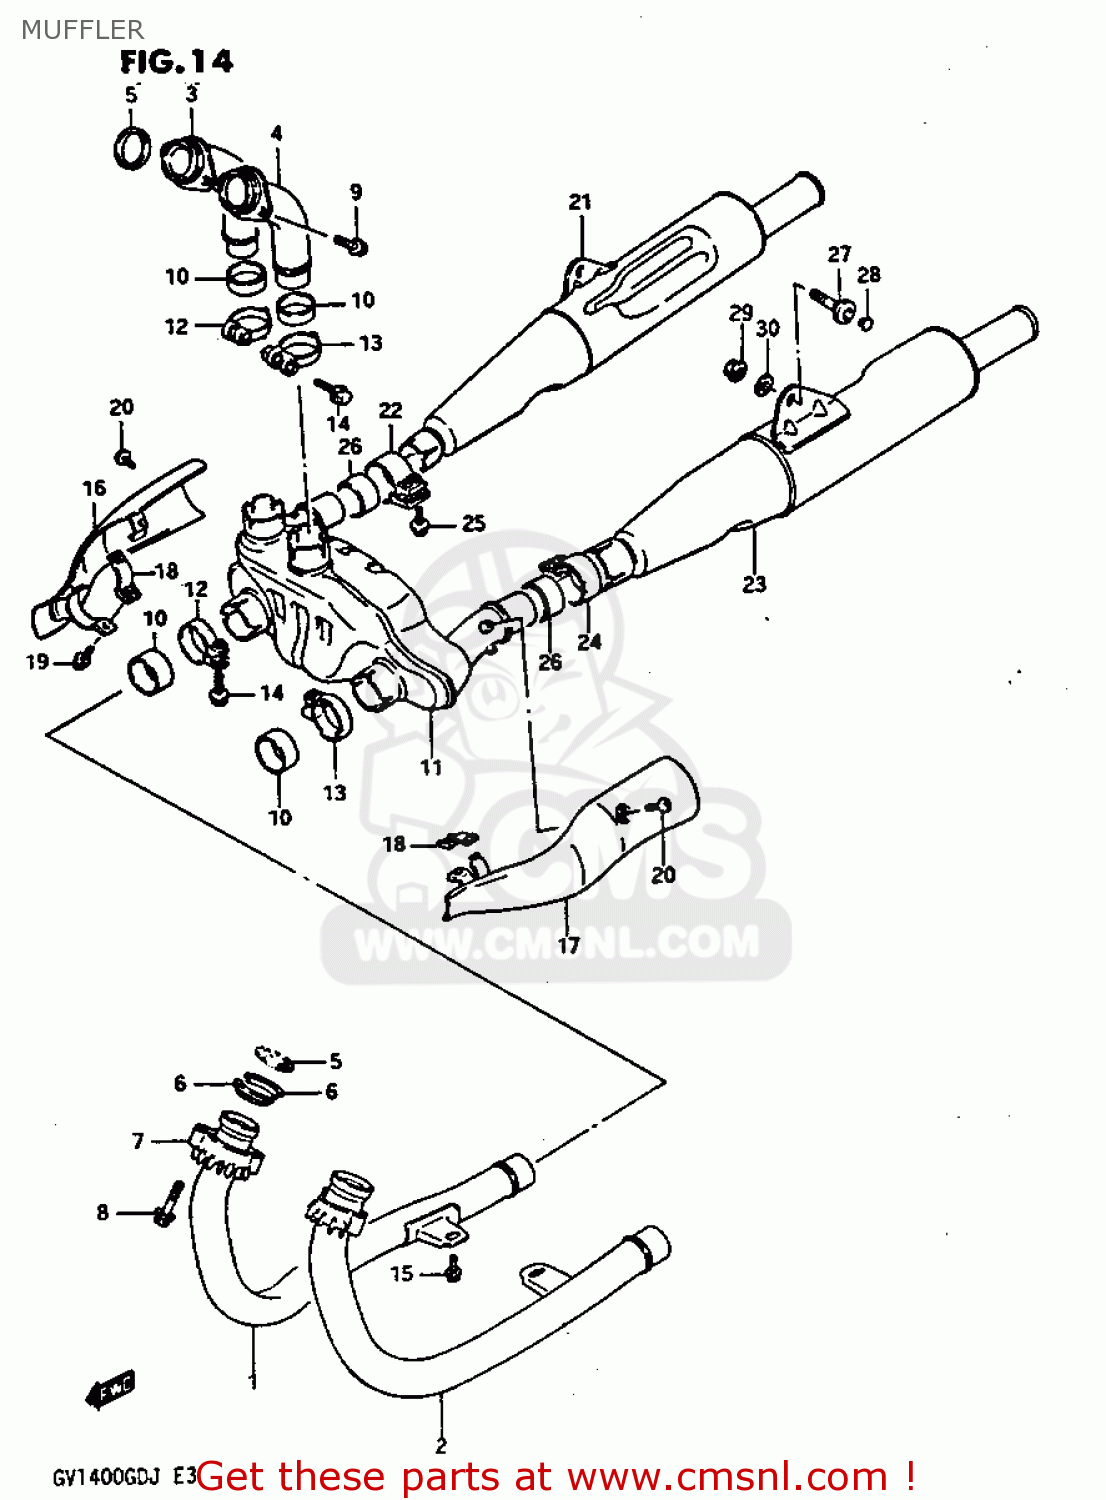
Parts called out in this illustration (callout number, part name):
1	PIPE COMP,EXHAUST,FRONT
2	PIPE,EXHAUST FR,L(#2)
3	PIPE,EXHAUST RR,R(#3)
4	PIPE,EXHAUST RR,L(#1)
5	GASKET,EXHAUST PIPE (NAS)
6	SPACER,EXHAUST PIPE
7	CLAMP(H:21)
8	BOLT
9	BOLT, REAR
10	CONNECTOR,MUFFLER
11	BODY ASSY,PRE MUFFLER
12	CLAMP,MUFFLER,R(L:42.7)
13	CLAMP,MUFFLER CONNECTOR
14	BOLT 8X40
15	BOLT
16	COVER,MUFFLER,R
17	COVER,MUFFLER,L
18	CLAMP,MUFFLER COVER
19	BOLT
20	SCREW(6X8)
21	MUFFLER,RIGHT
22	CLAMP,CONNECTOR MUFFLER
23	MUFFLER,LEFT
24	CLAMP,CONNECTOR MUFFLER,L
25	BOLT
26	CONNECTOR,MUFFLER
27	BOLT(10X50)
28	CAP(OD:12)
29	NUT
30	WASHER (10X18X3.2)
